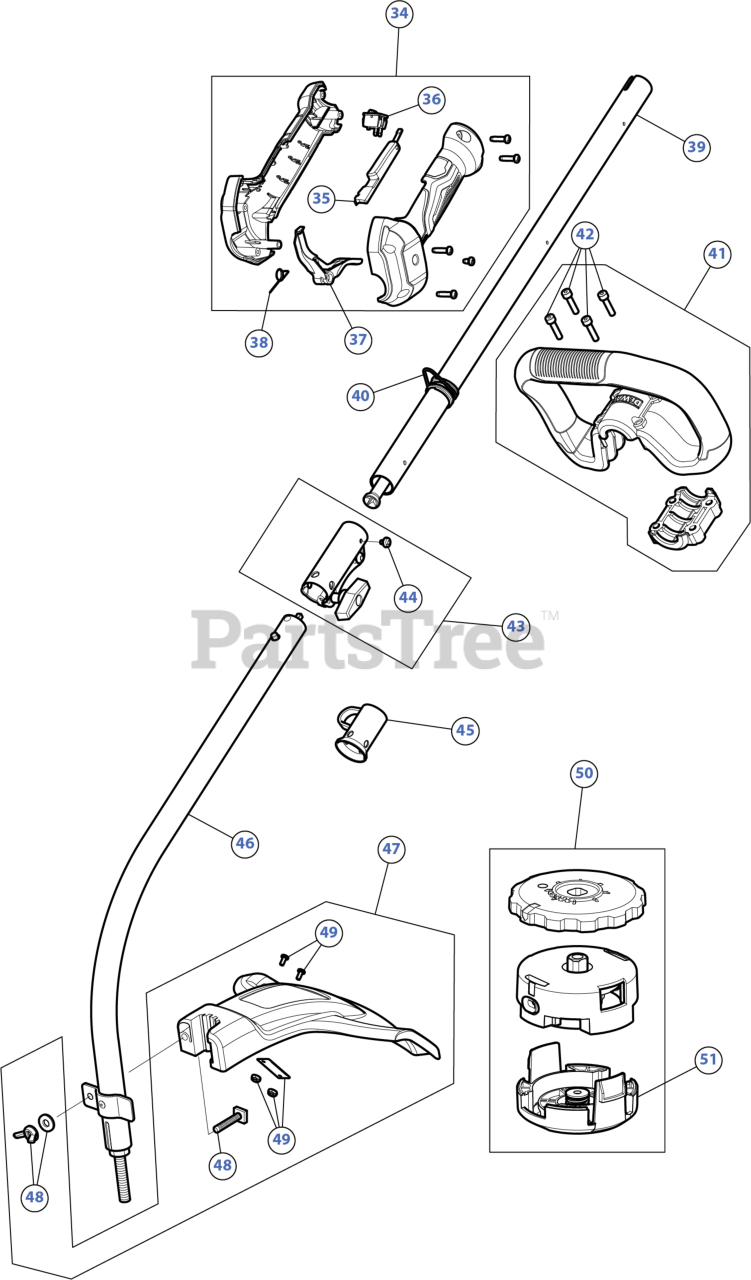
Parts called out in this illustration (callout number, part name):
34	THROTTLE GRIP
35	THROTTLE LOCK LEVER
36	SW, MOMENTARY ON/O
37	THROTTLE TRIGGER
38	TRIGGER SPRING
39	UPPER DRIVE SHAFT
40	CLAMP-SHOULDER STR
41	HANDLE
42	HANDLE BOLT
43	CLICK LINK
44	SCREW, 10-32X.250 TA
45	HANGER
46	LOWER SHAFT HOUSING
47	GUARD ASSEMBLY
48	BLADE GUARD MOUNTING HARDWARE
49	ASSEMBLY, BLADE
50	CUTTING HEAD
51	CAP SNAP SML:DEWALT
